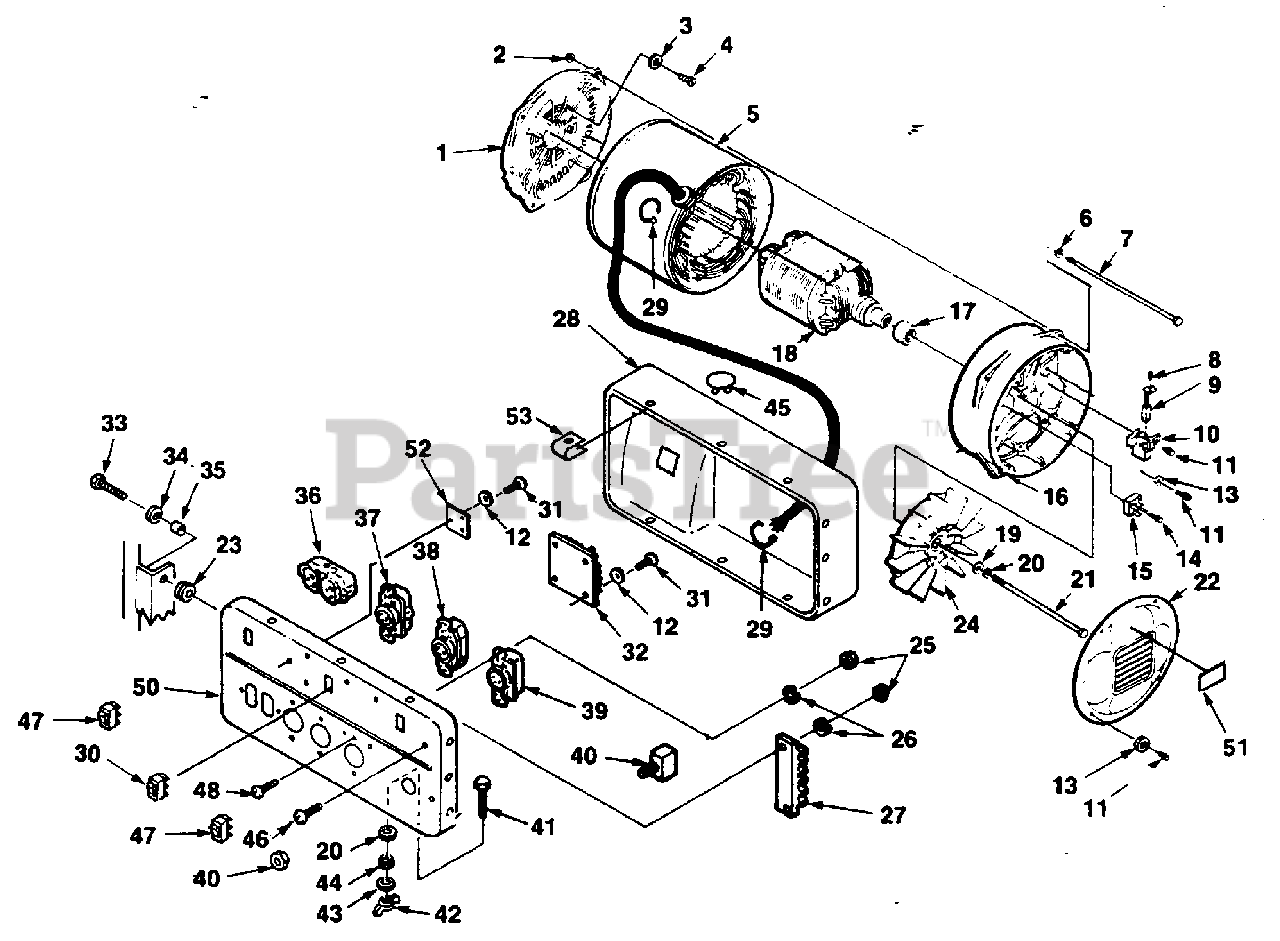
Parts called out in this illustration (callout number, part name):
1	END BELL
2	NUT-Hex 1/4-20
3	WASHER-Lock
4	SCREW-Hex hd 3/8-16 x 7/8
5	STATOR SHELL
6	WASHER-Lock Int. 1/4
7	BOLT-Stator
8	SCREW Mach. pan. hd. 8-32 x 3/8
10	BRUSH HOLDER
11	SCREW- Thd rolling
12	WASHER #8
13	WASHER #8
14	SCREW-Hex tap. 8-32 x 3/4
15	RECTIFIER
16	BRUSH HEAD
17	BEARING
19	WASHER-Flat 5/16
20	WASHER-Lock 5/16
21	BOLT-Rotor
22	BRUSH HEAD COVER
23	GROMMET
25	NUT-Hex 8-32
26	WASHER-Lock #8
27	BLOCK-Terminal
28	PANEL COVER
29	CABLE-Tie
30	SWITCH (DPDT)
31	SCREW-Pan hd. #8-32 x 1/2
32	VOLTAGE REGULATOR
33	SCREW-Pan Hd 1/4-20 x 3/4
34	WASHER-Flat
35	SLEEVE
36	RECEPTACLE
37	RECEPTACLE
38	RECEPTACLE
39	RECEPTACLE
40	CIRCUIT BREAKER
41	SCREW-Hex hd. 5/16-18 x 1/8
42	WING NUT- 5/16-18
43	WASHER-Lock 5/16
44	NUT-Hex 5/16-18
45	CLAMP-Cable
46	SCREW-Pan Hd 8-32 x 5/8
47	SWITCH-Rocker
48	SCREW- 8-32
49	RING-Locking
50	CONTROL PANEL
51	DECAL- Sch.
52	IDLE- Control
53	NUT- Speed
54	DECAL- Warning
